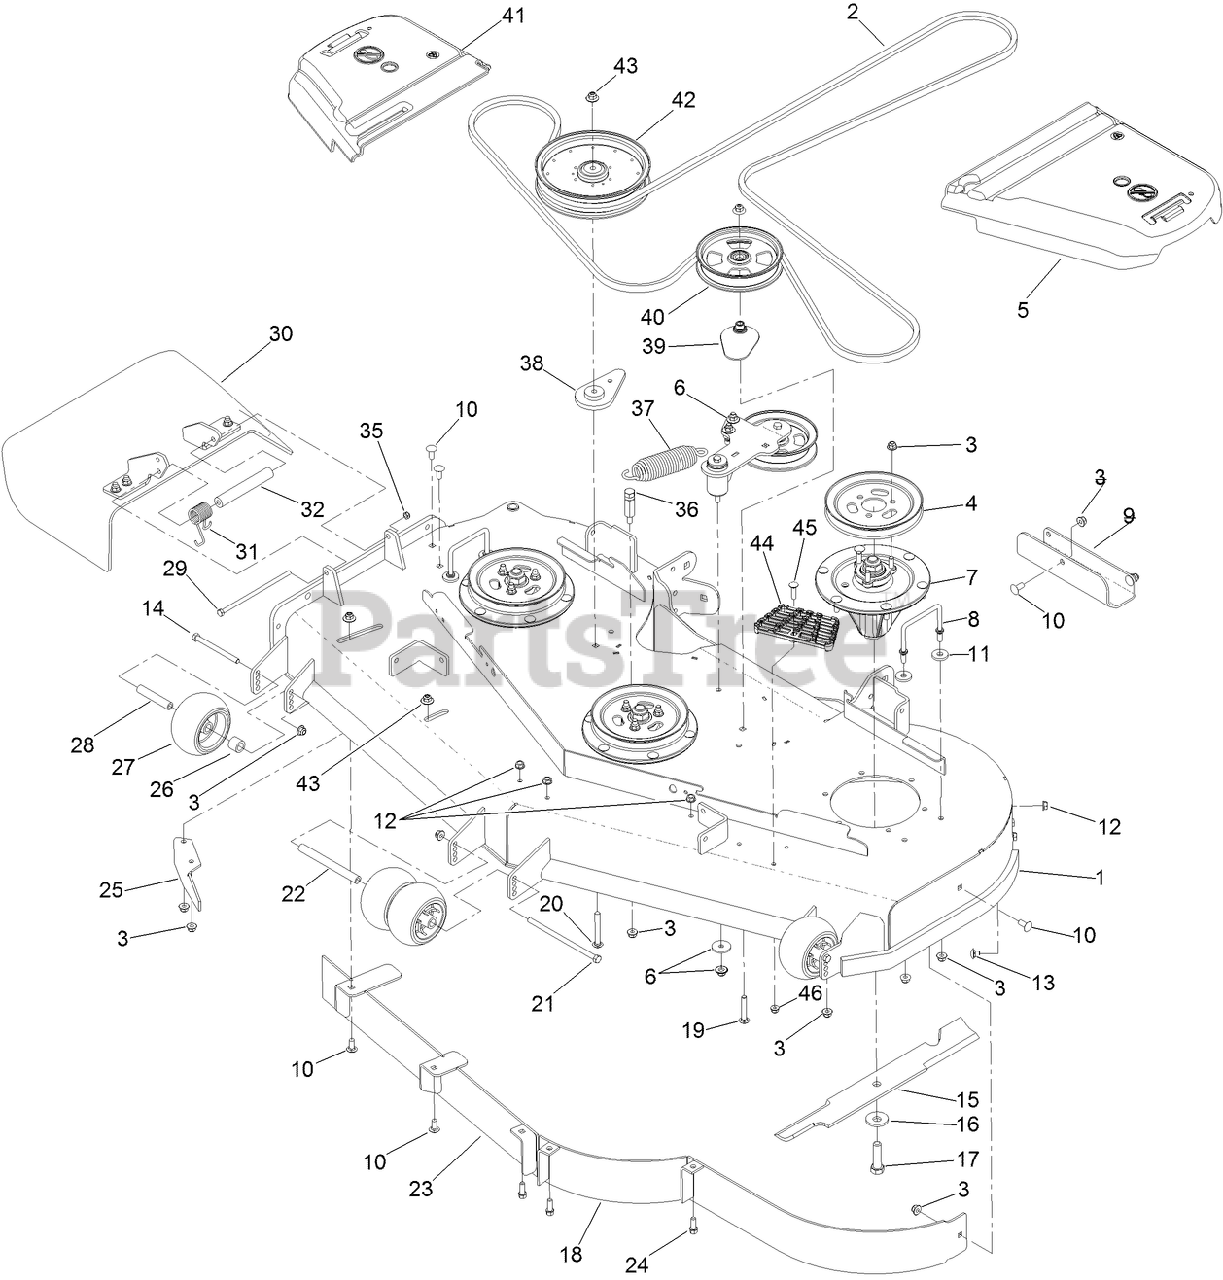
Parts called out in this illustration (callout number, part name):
1	DECK DECAL ASM
2	BELT-V
3	NUT-HF, NI
4	Pulley
5	COVER-BELT, LH
6	IDLER ARM ASM
7	SPINDLE ASM
8	WIREFORM-COVER
9	PLATE-SKID
10	SCREW-CARR
11	WASHER
12	NUT-HHF, WHIZ
13	SCREW-CARR
14	SCREW-HH
15	BLADE-HI FLOW
16	Washer-Blade Bolt, Heavy
17	SCREW-BLADE
19	BOLT-CARR, SHORT NECK
20	SCREW-CARR
21	SCREW-HH
22	SPACER-WHEEL
24	SCREW-HWH
25	BAFFLE-DISCHARGE
26	TUBE-SPACER
27	ROLLER-SCALP, ANTI
28	TUBE-SPANNER
29	SCREW-HH
30	RUBBER DEFLECTOR ASM
31	SPRING-TORSION
32	SPACER
35	NUT-LOCK, NI
36	ANCHOR-SPRING, TALL
37	SPRING-EXTENSION
38	SPACER-IDLER
39	SPACER-PULLEY
40	PULLEY-IDLER, FLAT
41	COVER-BELT, RH
42	PULLEY-IDLER
43	NUT-FLANGE, NI
44	STEP-DECK
45	SCREW-CARR
46	NUT-HF, NI
